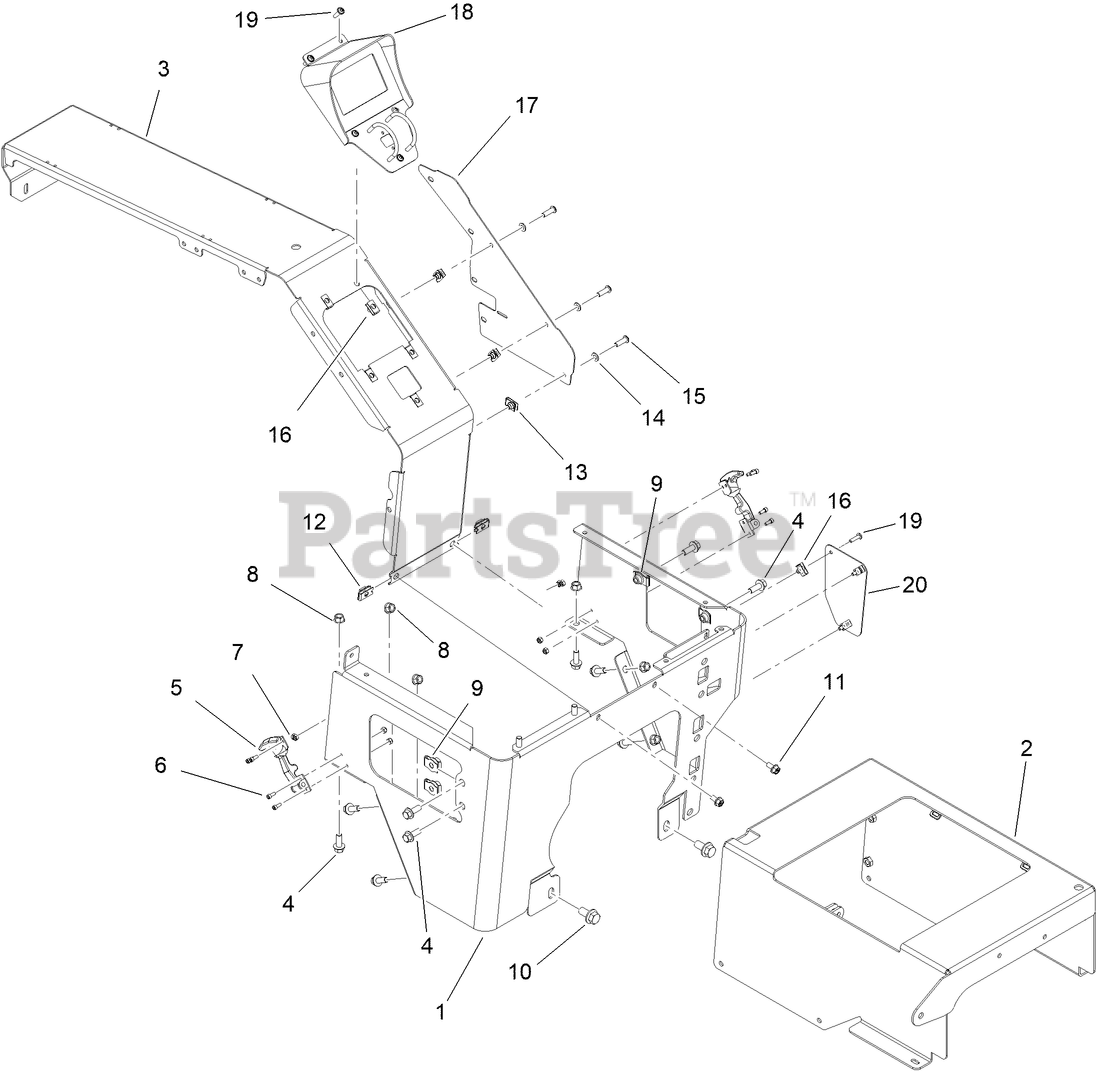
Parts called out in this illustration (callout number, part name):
1	CONSOLE-LOWER
2	SUPPORT, SEAT WELDED (TORO RED)
3	SUPPORT
4	SCREW-HHF
5	LATCH-FLEX, DRAW
6	SCREW-HSH
7	NUT-LOCK, NI
8	NUT-HF
9	NUT-TINNERMAN
10	SCREW-HHF
11	SCREW-HHF
12	NUT-THICK, TINNERMAN
13	NUT-U
14	Washer-Flat
15	SCREW-HSBH
17	PLATE-CONTROLS SIDE
18	MOUNT-DISPLAY
19	SCREW-HHF
20	COVER-ACCESS
